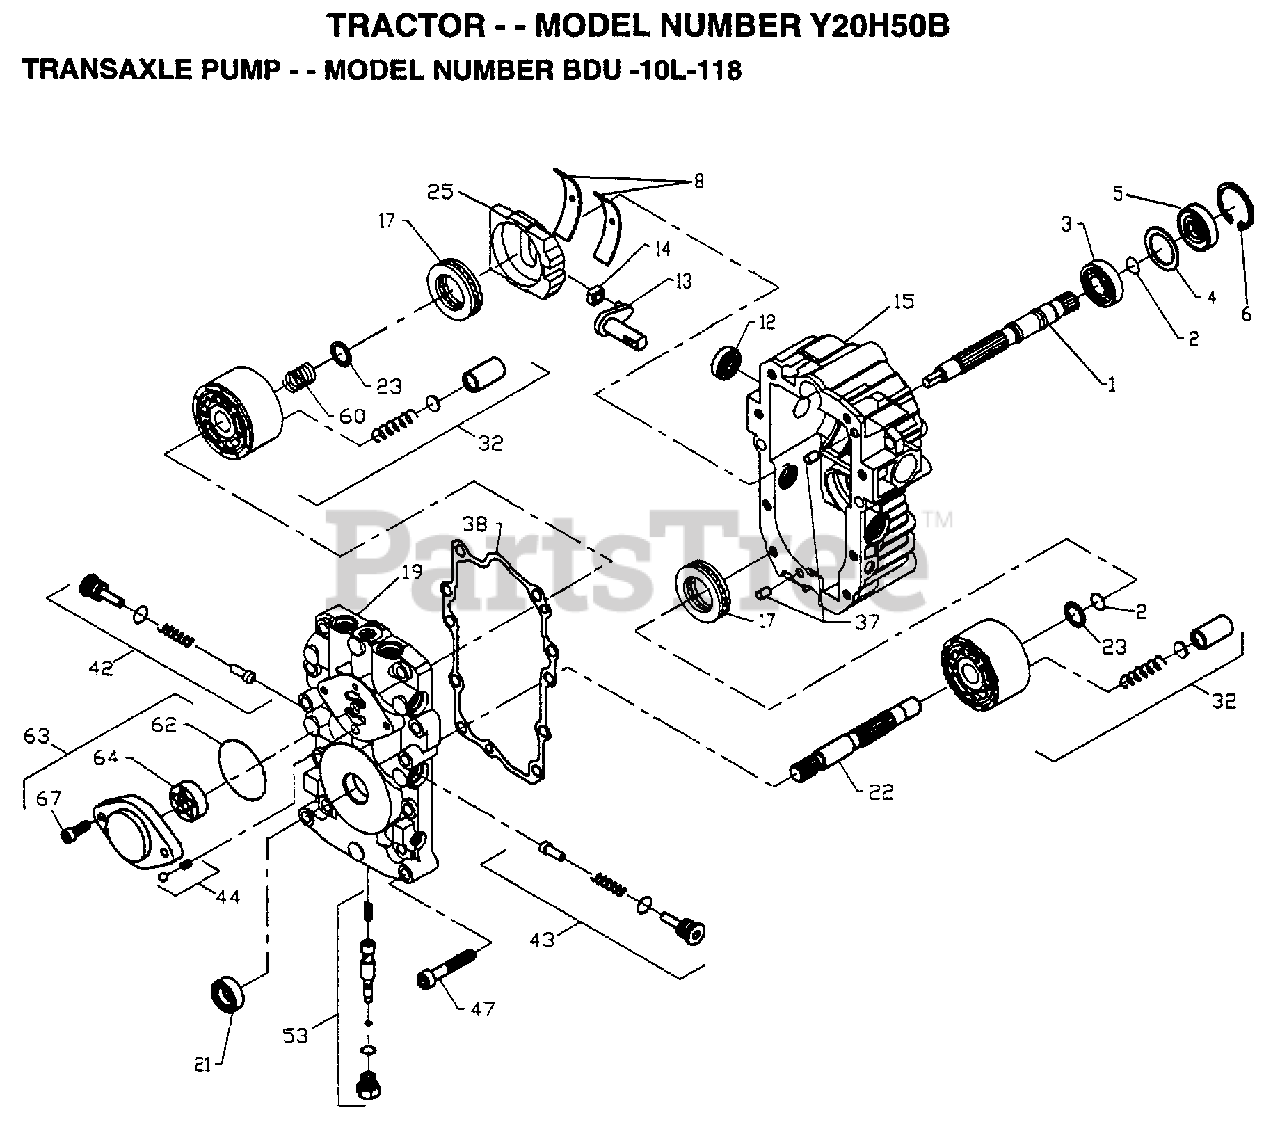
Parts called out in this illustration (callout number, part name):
1	SHAFT.PUMP.50158
3	BALL BEARING (HG#2003043)
14	GUIDE.2000015.HYD
15	KIT.HSG.2513035.
17	Bearing, Asm. Ball
19	KIT.CENT.2513006
21	LIP SEAL-9008000-0127
22	SHAFT.MOT.2003034
38	GASKET.2003060
42	KIT.VALVE.2510050
43	KIT.VALVE.2510050
44	KIT.RELI.2510011.
53	KIT,BYPASS VALVE(2513011)
62	0RING.90041011340
63	KIT.CHARG.2513027
64	GEROTOR.J1041008
67	SCREW.CAP.50095.
